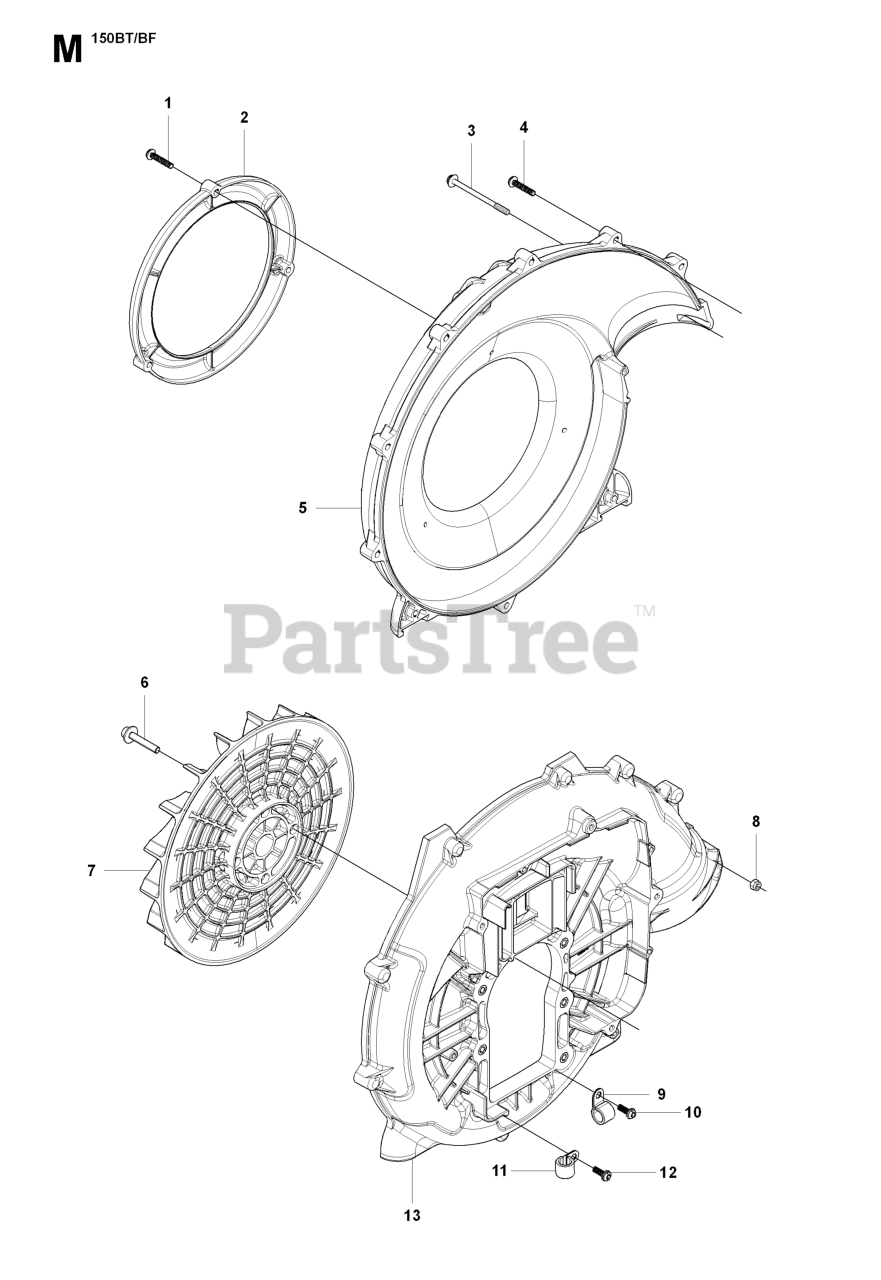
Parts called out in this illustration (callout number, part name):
1	TINE TI
2	PIN RETAINING SCREW
3	TINE.LH.12"(72L)
4	SPRING RETAINER
5	HUB.&.PLATE.ASM.LH
6	NUT
7	WASHER, LOCK 3/8
8	BOLT.HEX.001X20.37-24X1.ZINC
9	TINE TI
10	HUB & PLATE ASM RH
11	TINE.RH.12"(72R)
